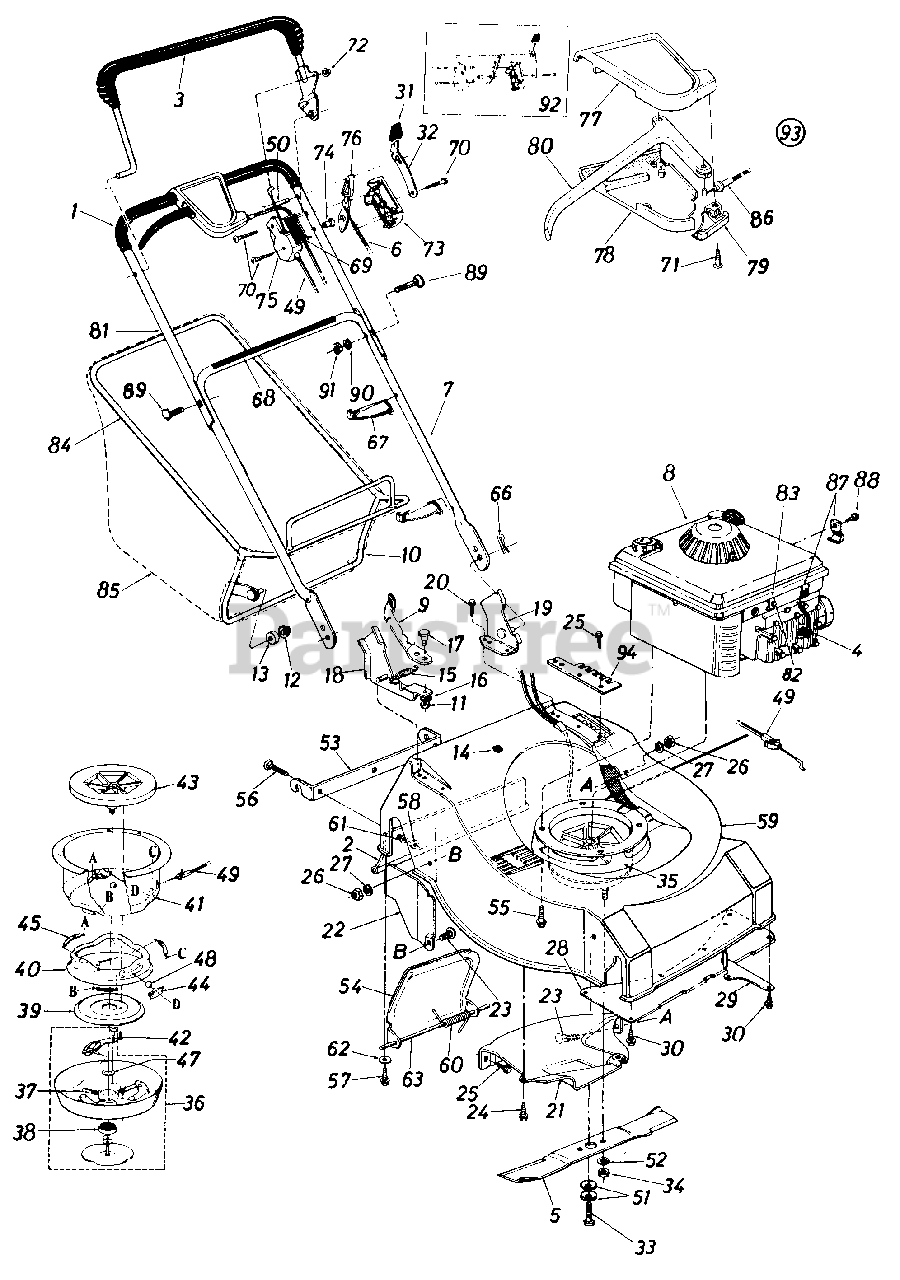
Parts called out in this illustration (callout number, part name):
2	Rear Flap Ass'y.
3	Controi Handle-L.H.
4	Spark Plug Insulator
5	22" Blade
6	Throttle Wire-58.0"
7	Lower Handle (Chrome)
8	Engine
9	Grass Catcher Lock Lever
12	Push Nut 3/8" Rod
13	Plastic Roller
15	Extension Spring
16	L-Wash. 5/16" I.D.
17	Shld. Bolt .437" Dia. x .162"
18	Handle Brkt. Ass'y.-R.H.
19	Handle Brkt. Ass'y.-L.H.
20	Hex Hd. Self-Tap Scr. 1/4-20 x 1.00" Lg.
21	Rear Baffle-L.H.
22	Side Baffle
23	Carriage Bolt 1/4-20 x .50" Lg.
24	Hex Wash. Hd. AB-Tap Scr. 1/4 x .62" Lg.
25	Hex Wash. Hd. Drill Scr. 1/4 x .75" Lg .
26	Hex Nut 1/4-20 Thd.
27	L-Wash. 1/4" I.D.
28	Front Cover Plate
29	Left Strap
30	Hex Wash. Hd. AB-Tap Scr. 1/4 x.62" Lg.
31	Spring Lever Knob
32	Lockout Spring
33	Hex Bolt 3/8-24 x 2.00" Lg. (Grade 8)
34	Hex Nut 3/8-24 Thd. (Grade 8)
35	Blade Brake Clutch Ass'y. Comp.
36	Clutch Blade Housing Ass'y.
37	Compression Spring .35" O.D. x 2.00" Lg.
38	Ball Brg. .669" I.D. x 1.574" O.D. x .47
39	Clutching Cone
40	Brake Cup Cone
41	Clutch Housing
42	Hex TT-Tap L-Scr. 1/4-20 x .75" Lg.
43	Fan Adapter
44	Ball Block
45	Extension Spring .35" O.D. x 1.75" Lg.
47	Fl-Wash. .690" I.D. x 1.060 O.D. x .030
48	Steel Ball .500" Dia.
49	Clutch Cable-46"
50	Lock Pin .314" Dia. x 1.70
51	Bell-Wash. .400" I.D. x .88" O.D.
52	L-Wash. 3/8" I.D.
53	Grass Catcher Hitch Brkt.
54	Chute Door
55	Hex Wash. Hd. TT-Tap Scr. 3/8-16 x 1.00" Lg.
56	Carriage Bolt 1/4-20 x 1.0" Lg.*
57	Hex Wash. Hd. "AB"-Tap Scr. 1/4 x.62"
58	Sems Nut 1/4-20 Thd.
59	22" Deck Ass'y.
60	Torsion Spring .34" I.D. x 2.38" Lg.
61	Fl-Wash. .281" I.D. x .73" O.D. x .063
62	Fl-Wash. .285" I.D. x 1.25" O.D. x .060
63	Rod .25" Dia. x 8.25" Lg.
66	Intern. Cot. Pin 5/16" Dia.
67	Cable Tie
68	Ins{ruction Label-Handle
69	Control Label-Throttle
70	Truss Mach. B-Tap Scr. #12 x 1.50" Lg.
71	Flat C-Sunk AB-Tap Scr. #10 x.75" Lg.
72	Push Cap
73	Control Panel Half
74	Control Disc Pin
75	Clutch Panel Half
76	Throttle Control Lever
77	Control Cover Half-Upper
78	Control Cover Half-Lower
79	Cable Mtg. Cap
80	Control Lever
81	Upper Handle (Chrome)
82	Hex B-Tap Scr. #10 x .62"
83	Casing Clamp
84	Grass Catcher Upper Frame
85	Grass Bag (w/o Flip Top)
86	Self-Propelled Clutch Cable-50.0" Lg.
87	Casing Clamp
88	Hex B-Tap Scr. #10 x .38" Lg.
89	Curved Carriage Bolt 5/16-18 x 1.38" Lg.
90	L-Wash. 5/16" I.D.
91	Hex Nut 5/16-18 Thd.
92	Kit-Control Housing Comp.
93	Kit-Clutch Housing Comp.
94	Reinforcing Brkt.
